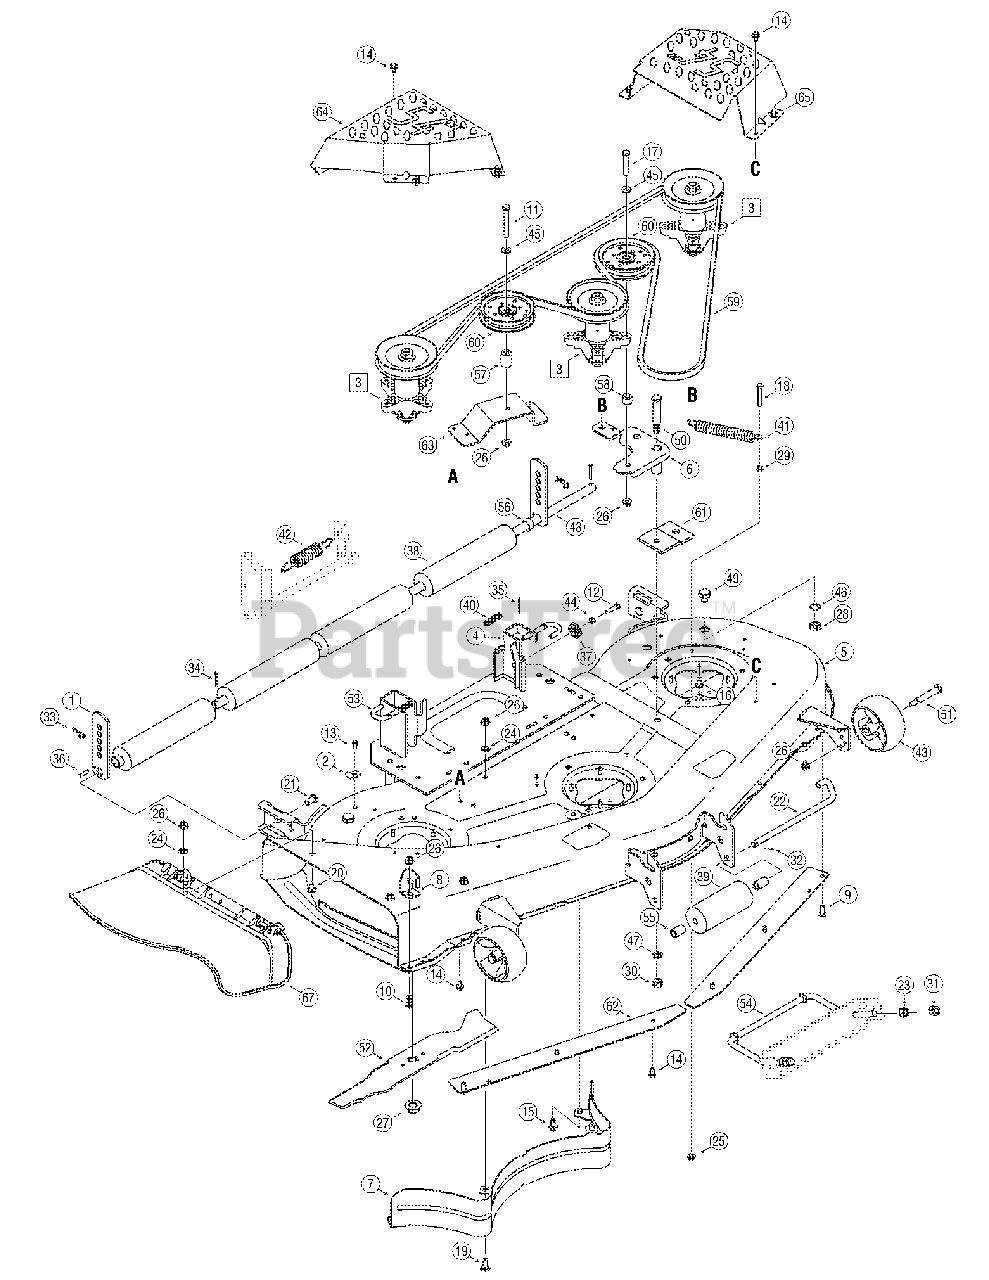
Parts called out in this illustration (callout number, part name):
2	Retainer Hook Bracket
3	Pulley Spindle Assy. 5.39 x.5625
9	HH Cap Screw 3/8-16 x.75
10	HH Cap Screw 3/8-16 x 1.00
11	HH Cap Screw 3/8-16 x 3.00
12	HH Cap Screw 5/16-18 x 1.25
13	TT Screw 1/4-20 x.500
14	TT Screw 5/16-18 x.500
15	TT Screw 3/8-16 x.750
16	LD Screw 5/16-18 x.750
17	HH Cap Screw 3/8-16 x 2.25
18	HH Cap Screw 5/16-18 x 2.00
19	Carriage Bolt 3/8-16 x 1.00
20	Carriage Bolt 3/8-16 x.75
21	Clevis Pin.50 x.78
22	Roller Pin.5" x 10.06
23	Hex Nut 1/2-13
24	Push Nut 3/8
25	Flange Lock Nut 5/16-18
26	Flange Lock Nut 3/8-16
27	Flange Nut 5/8-18
28	Hex Nut M16-1.5 DIN 936
29	Hex Nut 5/16-18
30	Hex Lock Nut 1/2-13
31	Hex Lock Nut 1/2-13
32	Cotter Pin 3/32 x 1.0
33	Click Pin.092 x 1.64
34	Cotter Pin 5/32 x 1.25
35	Cotter Pin 1/8 x 1.25
36	Spring Pin 1/4 x 1.00
37	Deck Adjustment Gear
38	Deck Roller
39	Front Roller
40	Compression Spring.531 x 1.75
41	Extension Spring.94 x 6.74
42	Extension Spring 1.15 x 5.99
43	Deck Wheel 5.0 Dia. Ball
44	Lock Washer 5/16
45	Flat Washer.406 x.875 x.059
46	Lock Washer
47	Lock Washer 1/2
48	Shaft.750 x.47.12
49	Screw Plug M16 x 1.5
50	Shoulder Screw.625 x 2.50 x 1/2-13
51	Shoulder Screw 1/2 x 2.50
52	Blade18.50" Long
53	Deck Handle Rod
54	Front Deck Adjustment Rod
55	Spacer.550 ID x.750 OD x 1.125
56	Spacer.82 ID x 1.00 OD x.53
57	Spacer.380 x.900 x 1.313
58	Spacer 385 ID x.88 x.64
59	V-Belt
60	Idler Pulley 4.25
67	Chute Assembly
